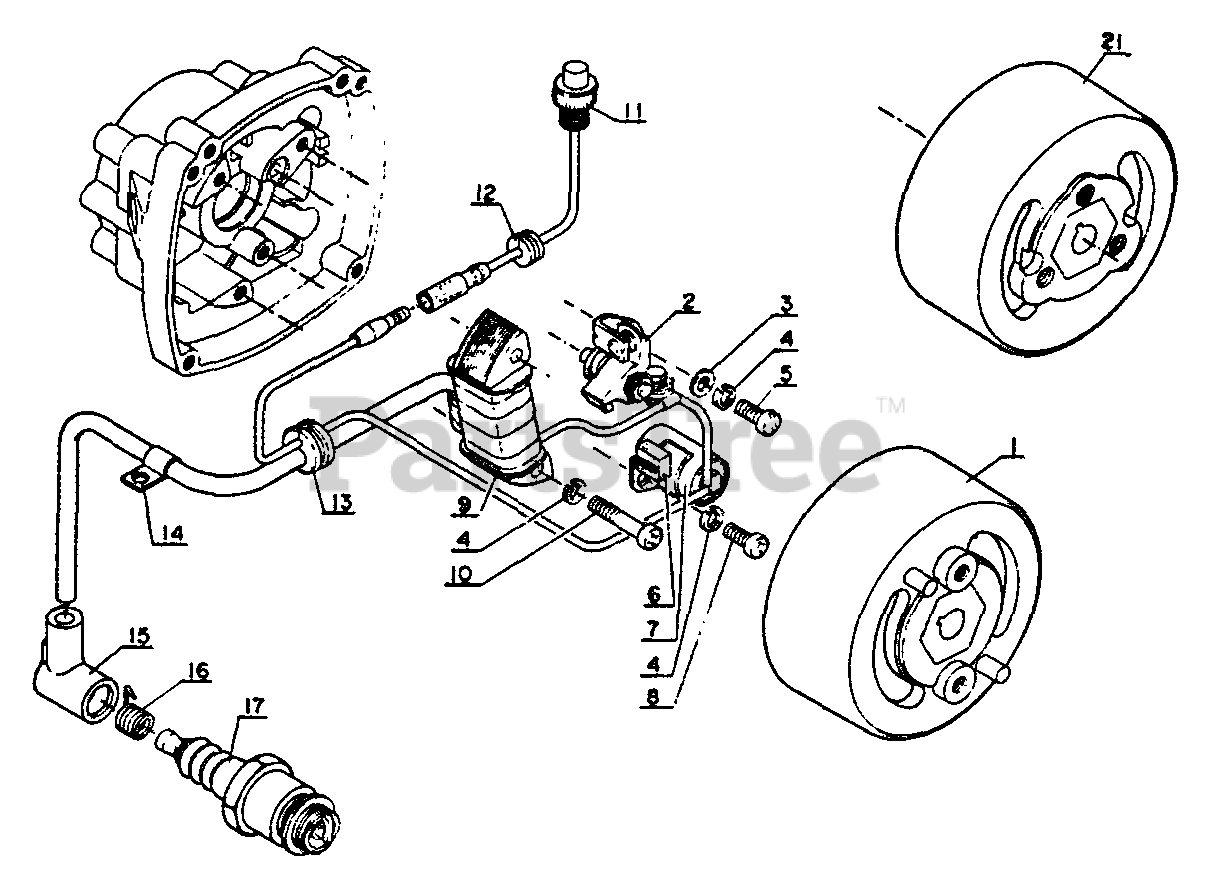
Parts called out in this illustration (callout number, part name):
1	FLYWHEEL
2	CONTACT POINT SET
3	WASHER - 4
4	LOCKWASHER - 4
5	SCREW - 4X8
7	CONDENSER
8	SCREW - 4X8
9	COIL, IGNITION
10	SCREW - 4X20
11	BUTTON, STOP
12	GROMMET
14	CLAMP
15	CAP, SPARK PLUG
16	TERMINAL, SPARK PLUG CAP
17	SPARK PLUG -- BM-6A
21	FLYWHEEL
